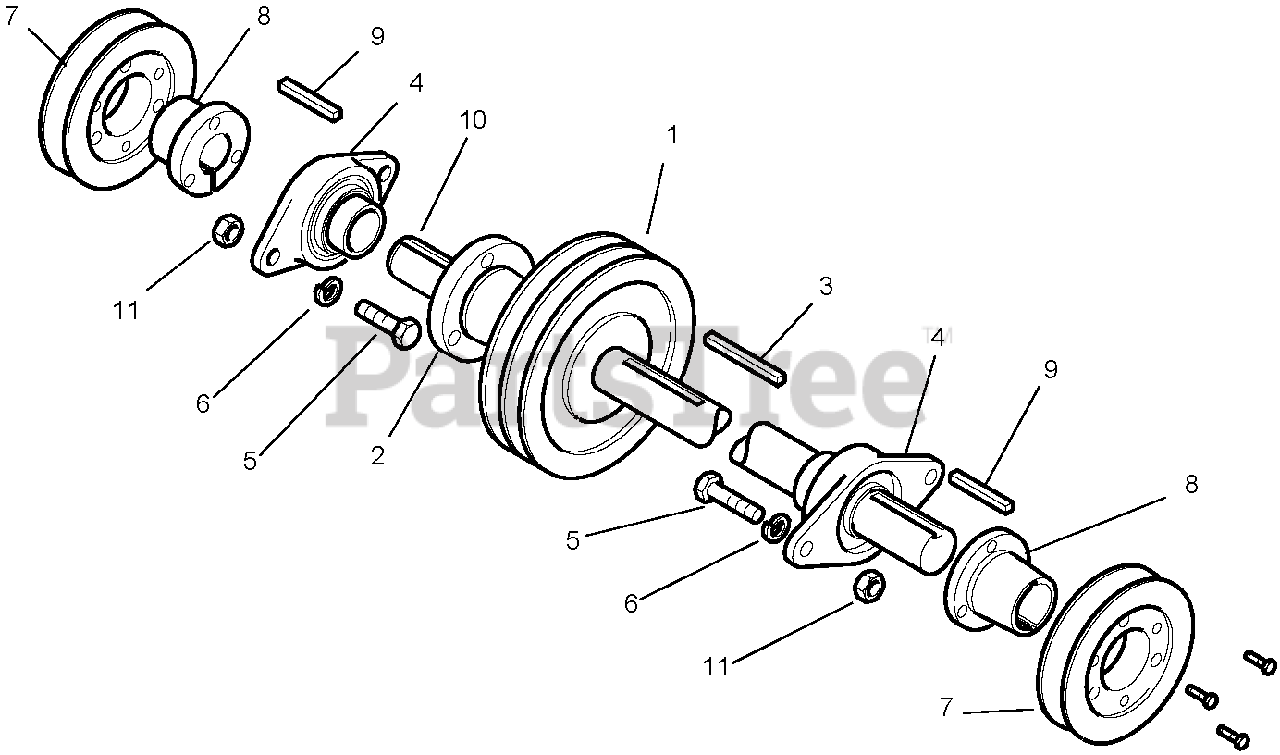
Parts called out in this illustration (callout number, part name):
1	Pulley, 2-Belt 6.6 PD
2	Bushing, Split Tapered
3	Key, Pulley
4	Bearing Flange, 2-Bolt
5	Cap Screw, Hex Head .437-14 x 1.25
6	Washer, Lock .437
7	Pulley, 1-Belt 4.4 PD
8	Bushing, Split Tapered
9	Key, Square .25 x .25 x 1
10	Jackshaft, Front
11	Nut, Hex .437
